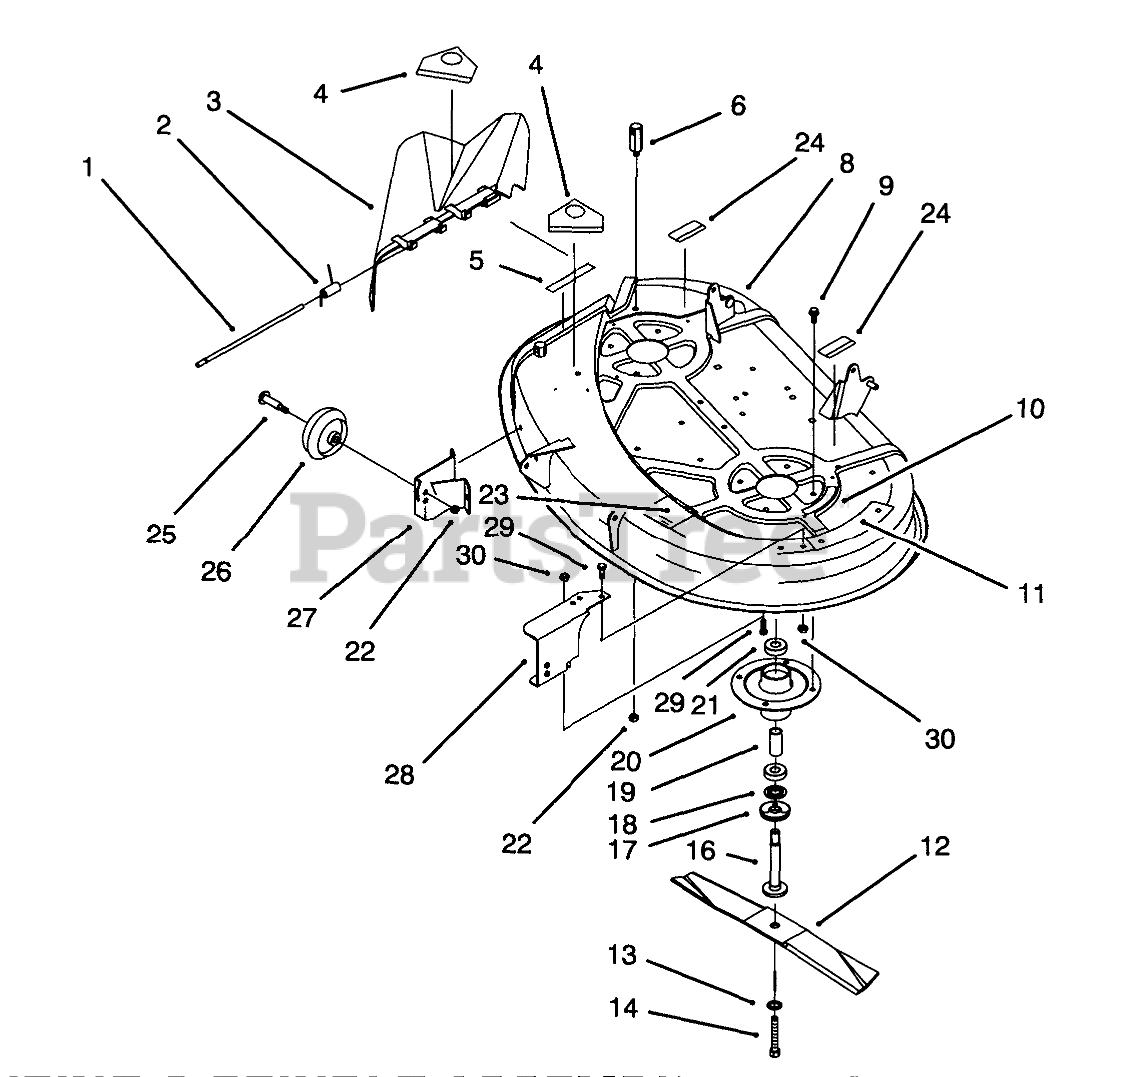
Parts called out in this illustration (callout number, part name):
1	ROD-HINGE DEFLECTOR
2	SPRING
3	Deflector-Deck
4	DECAL-DANGER
5	DECAL-DANGER, DEFLECTOR
6	REAR PIVOT POST (PLTD)
8	Deck-38"
9	SCREW-TAPTITE
10	DECAL-DANGER, SHIELD
11	DECAL-DANGER
12	Blade
13	WASHER-BELLEVILLE
14	SCREW-HH
16	SHAFT-SPINDLE
17	SHIELD-BEARING
18	SPACER
19	SPACER
20	HOUSING-SPINDLE
21	BEARING-BALL
22	NUT-LOCK, NI
23	Decal-Routing
24	DECAL-WARNING
25	SCREW-SHOULDER, HWH
26	WHEEL-GAGE
27	Bracket-R.H.
28	LH WHEEL DECK BRKT
29	SCREW-HH
30	NUT-LOCK, NI
